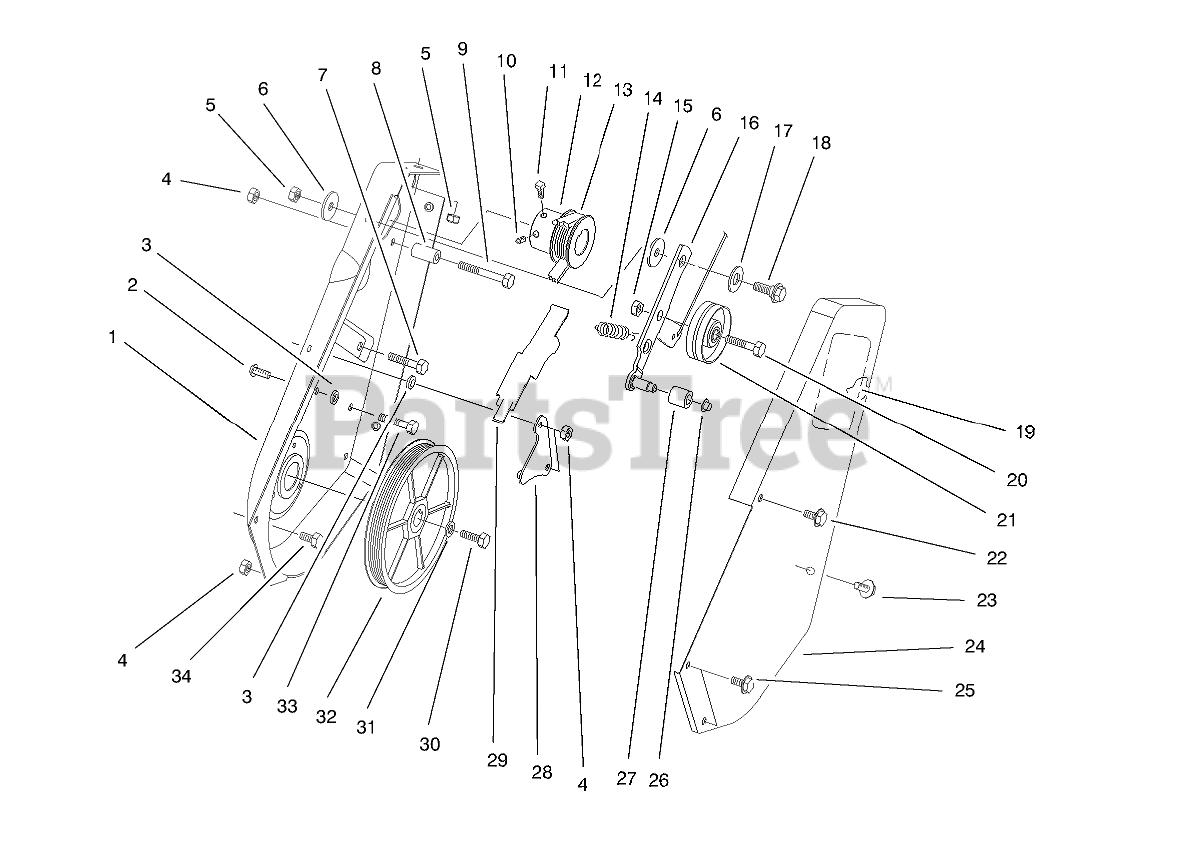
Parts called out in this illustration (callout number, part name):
1	Sideplate-LH
2	SCREW-HSBH
3	SPACER-PLATE, PIVOT
4	NUT-LOCK, NI
5	NUT-LOCK, NI
6	WASHER-PIVOT
7	SCREW-HH
8	SLEEVE-GUIDE, BELT
9	SCREW-HH
10	SCREW-HSH
11	SCREW-SQH
12	ENGINE PULLEY
13	BELT - DRIVE
14	SPRING-EXTENSION
15	NUT-LOCK, CONE
16	IDLER ARM ASM
17	WASHER
18	SCREW-SHOULDER
19	DECAL
20	SCREW-HH
21	PULLEY-IDLER
22	SCREW-HWH, TAP
23	SCREW
24	Cover-Drive
25	SCREW-HWH
26	NUT-PUSH
27	ROLLER-BRAKE
28	PIVOT PLATE ASM
29	BRAKE-ARM
30	SCREW-HH
31	WASHER-BELLEVILLE
32	ROTOR PULLEY ASY
33	SCREW-HH
34	SCREW-SHH
35	Decal-Hot
36	DECAL-HOT
